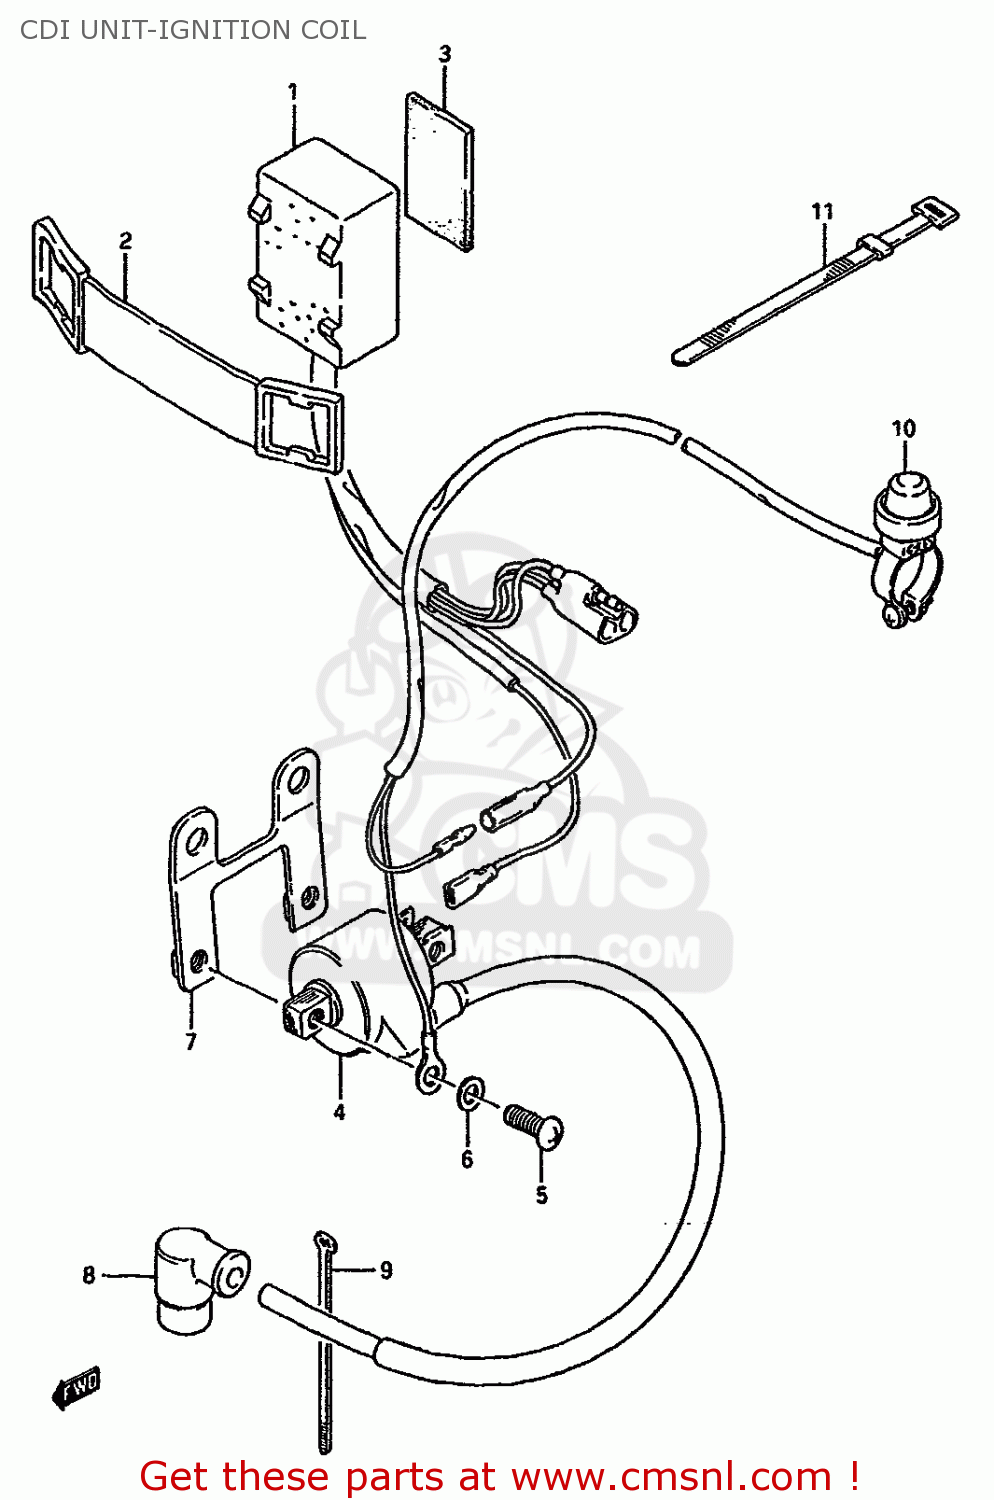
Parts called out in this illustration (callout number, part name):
1	CDI UNIT
2	BAND
3	PROTECTOR(170X95X3.0)
4	COIL ASSEMBLY,IGNITION
5	SCREW
6	WASHER,LOCK
7	BRACKET,IGNITION COIL
8	CAP,SPARK PLUG
9	CLAMP
10	SWITCH ASSEMBLY
11	CLAMP(L:120)
